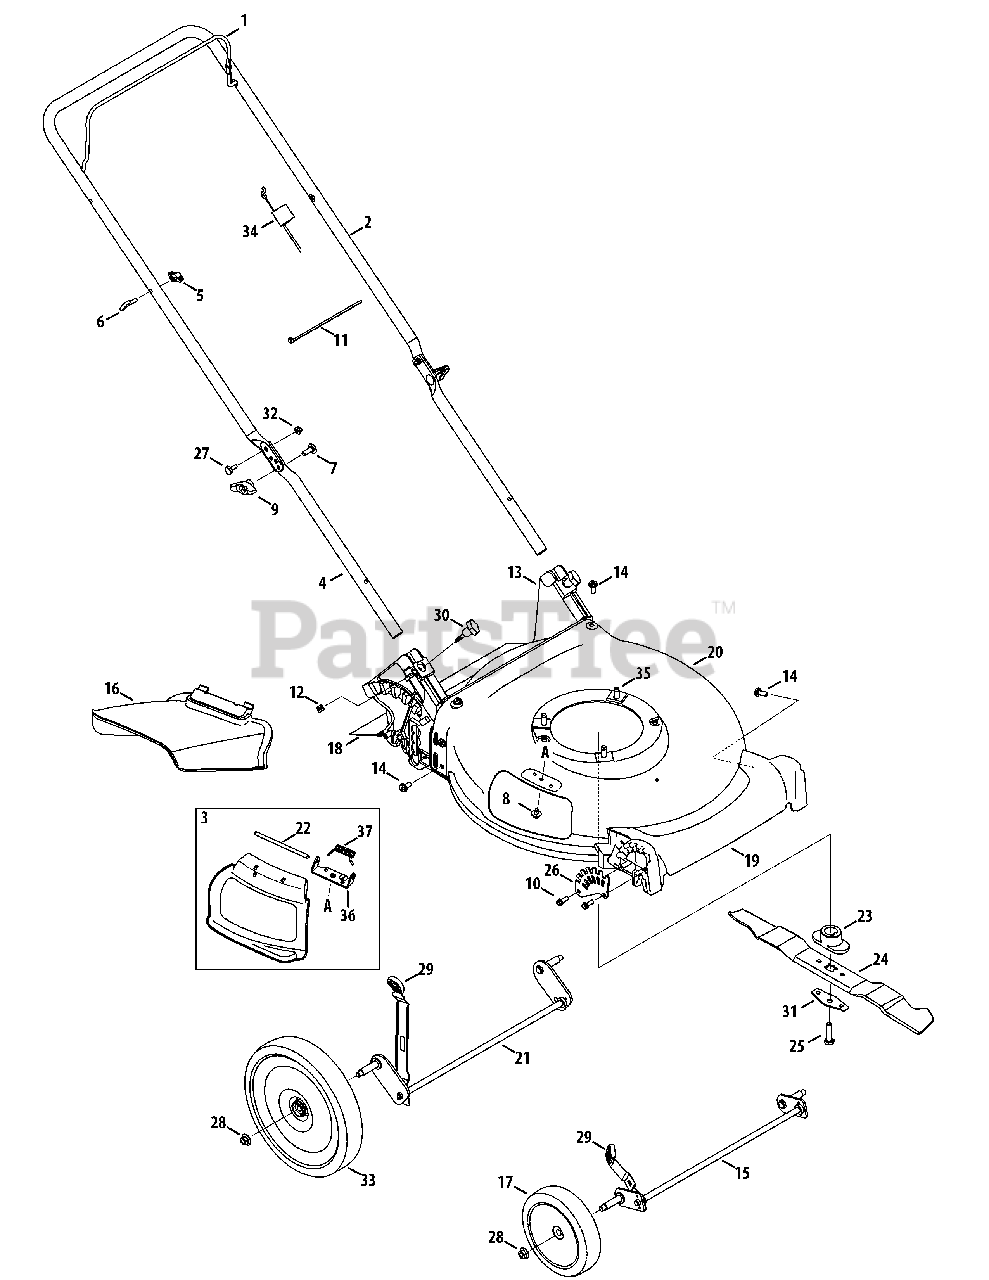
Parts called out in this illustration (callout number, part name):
1	Blade Control
2	Upper Handle
3	Hinged Mulch Plug Assembly
4	Lower Handle
5	Wing Nut
6	Rope Guide
7	Carriage Screw ,5/16-18
8	Screw, 1/4-20 x .500
9	Wing Knob
10	Screw, 1/4-15 x .750
11	Cable Tie
12	Nut, Sq., 1/4-20
13	Rear Baffle
13	Rear Baffle (Lowes)
14	Screw, 5/16-14 x .750
15	Front Axle Assembly
16	Side Chute
17	Front Wheel, 7 x 1.8, Gray
18	Trail Shield
19	Front Cover
20	Deck - 21" - Red
20	Deck - 21" - Green
21	Rear Axle Assembly
22	Hinge Pin
23	Blade Adapter
24	Mulching Blade
25	Screw , 3/8-24 x 1.50
26	Front Height Adjuster Plate
27	Sldr. Screw, .375 x .126 x 1/4-20
28	Flange Lock Nut, 3/8-16
29	Adjustment Lever Knob
30	Wing Nut
31	Blade Bell Support
32	Nut, Flange Lock, 1/4-20
33	Rear Wheel, 11 x 1.8, Gray
34	Control Cable, 37.25"
34	Control Cable, 48"
35	TT Sems Screw, 3/8-16 x 1.0
36	Chute Deflector Bracket
37	Torsion Spring
